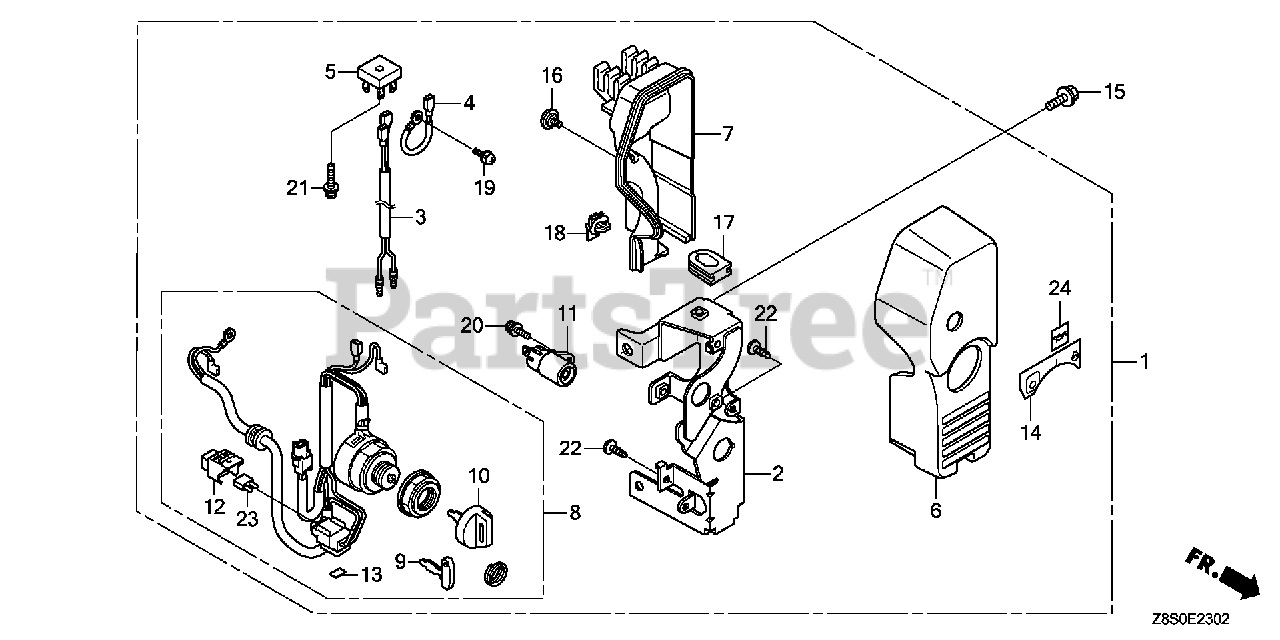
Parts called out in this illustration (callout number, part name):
1	BOX ASSY., CONTROL
2	BRACKET, SWITCH BOX
3	WIRE, CHARGE COIL
4	WIRE, GROUND
6	PANEL, CONTROL
7	COVER, CONTROL
8	SWITCH ASSY., COMBINATION (IND)
10	KEY ASSY., COMBINATION SWITCH (BLACK)
11	INDICATOR ASSY.
12	COVER ASSY., FUSE
13	LABEL, FUSE (30A)
14	MARK, ENGINE SWITCH
15	BOLT, FLANGE (6X12) (CT200)
16	SCREW, SPECIAL (6X8)
17	GROMMET, CONTROL BOX
18	CLIP, CONNECTOR (BLACK)
19	SCREW-WASHER (4X8)
20	SCREW-WASHER (4X10)
21	SCREW-WASHER (4X20)
22	SCREW, TAPPING (4X14) (PO)
23	FUSE, MINI (30A)
24	MARK, OIL CAUTION
